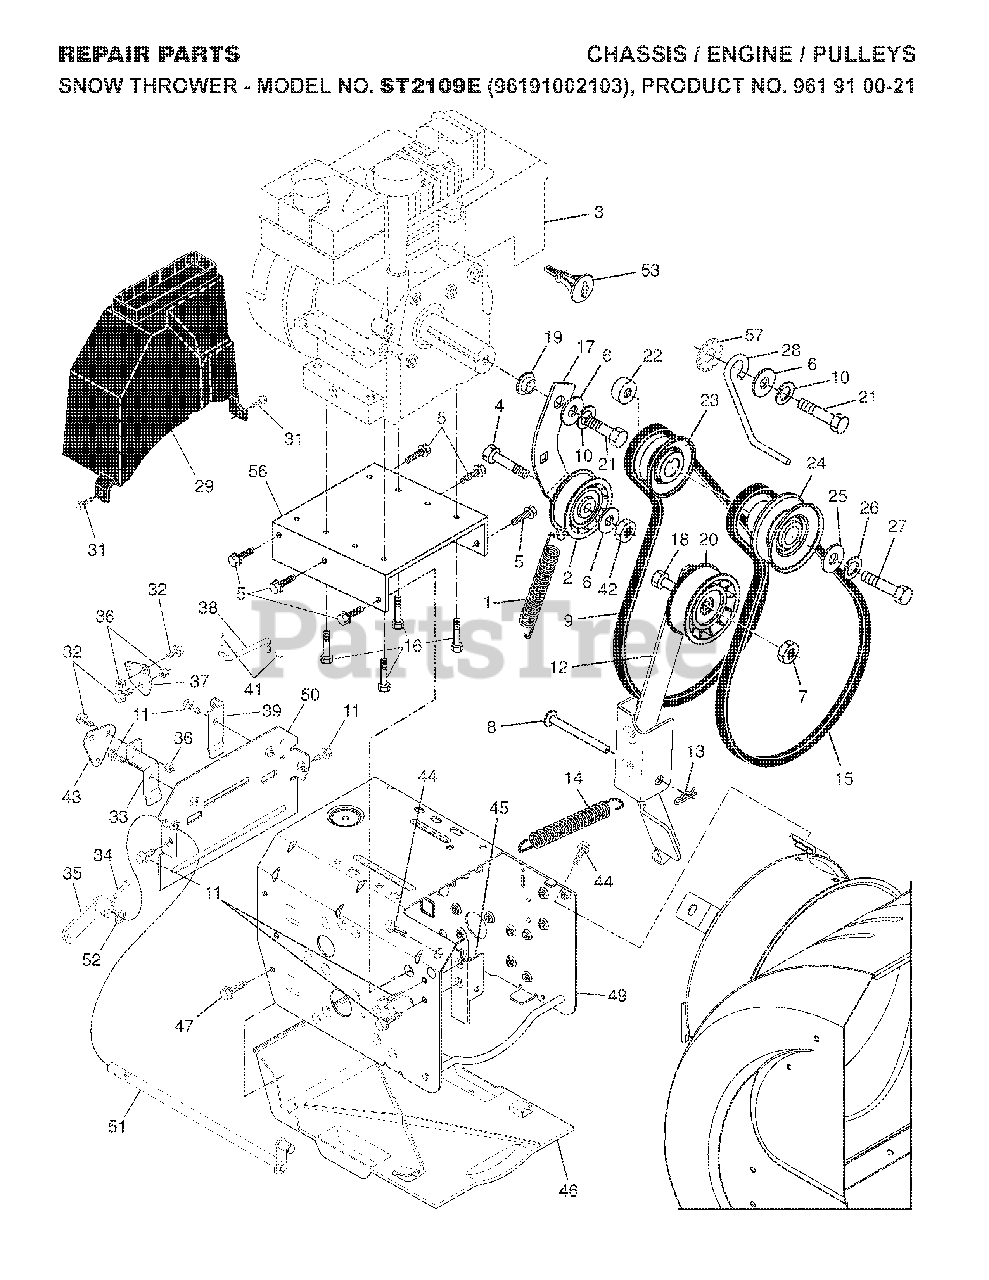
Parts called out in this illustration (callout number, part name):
1	RP SPRING, TRACTION IDLER
2	PULLEY.W/SPACER.2.25
4	BOLT.5/16-18X1-1/4 FULL.THREAD
5	SELF-TAPPING SCREW 5/16-18X3/4
6	STEEL WASHER
7	LOCKNUT 5/16-18
8	PIN, IDLER PIVOT
10	LOCKWASHER
12	ARM PAD ASSY
13	RETAINER CLIP PM
14	SPRING, BRAKE
15	BELT-V.IMPELLER.HS
16	BOLT 3/8-16X1-1/8
17	ARM, IDLER
18	HEX BOLT
19	BUSHING, IDLER PIVOT
20	PULLEY.W/SPACER.2.75
22	SPACER.ENGINE.PULLEY
23	PULLEY, ENGINE TRACTION DRIVE
24	PULLEY
25	WASHER, FLAT 3/8
26	LOCKWASHER
27	SCREW, HEX HD 3/8-24 X 1-3/8
28	GUIDE BELT
29	COVER.BELT.HS
31	SCREW
32	BOLT.SHOULDER.3/X.25
33	BRACKET.SHIFTER.PLATE.BZP
34	CLEVIS PIN
35	ARM, AUGER CONTROL
36	NUT.HEX.FLANGE.1/4
37	PLATE.CLUTCH.BZP
38	LINK, SPEED CONTROL
39	BRACKET.CLUTCH.PLATE.BZP
41	RETAINER CLIP
42	LOCKNUT 5/16-18
43	PLATE.SHIFTER.BZP
44	SCREW 3/8-16X1
45	BRACKET, IDLER PIVOT
46	PAN.BOTTOM.PLASTIC
47	SCREW, HEX HEAD, TAPPING
51	SHAFT, AUGER CONTROL
52	THRUST WASHER
53	KEY.PUSH/PULL.B&S.
57	WASHER EXT TOOTH LOCK 5/16
